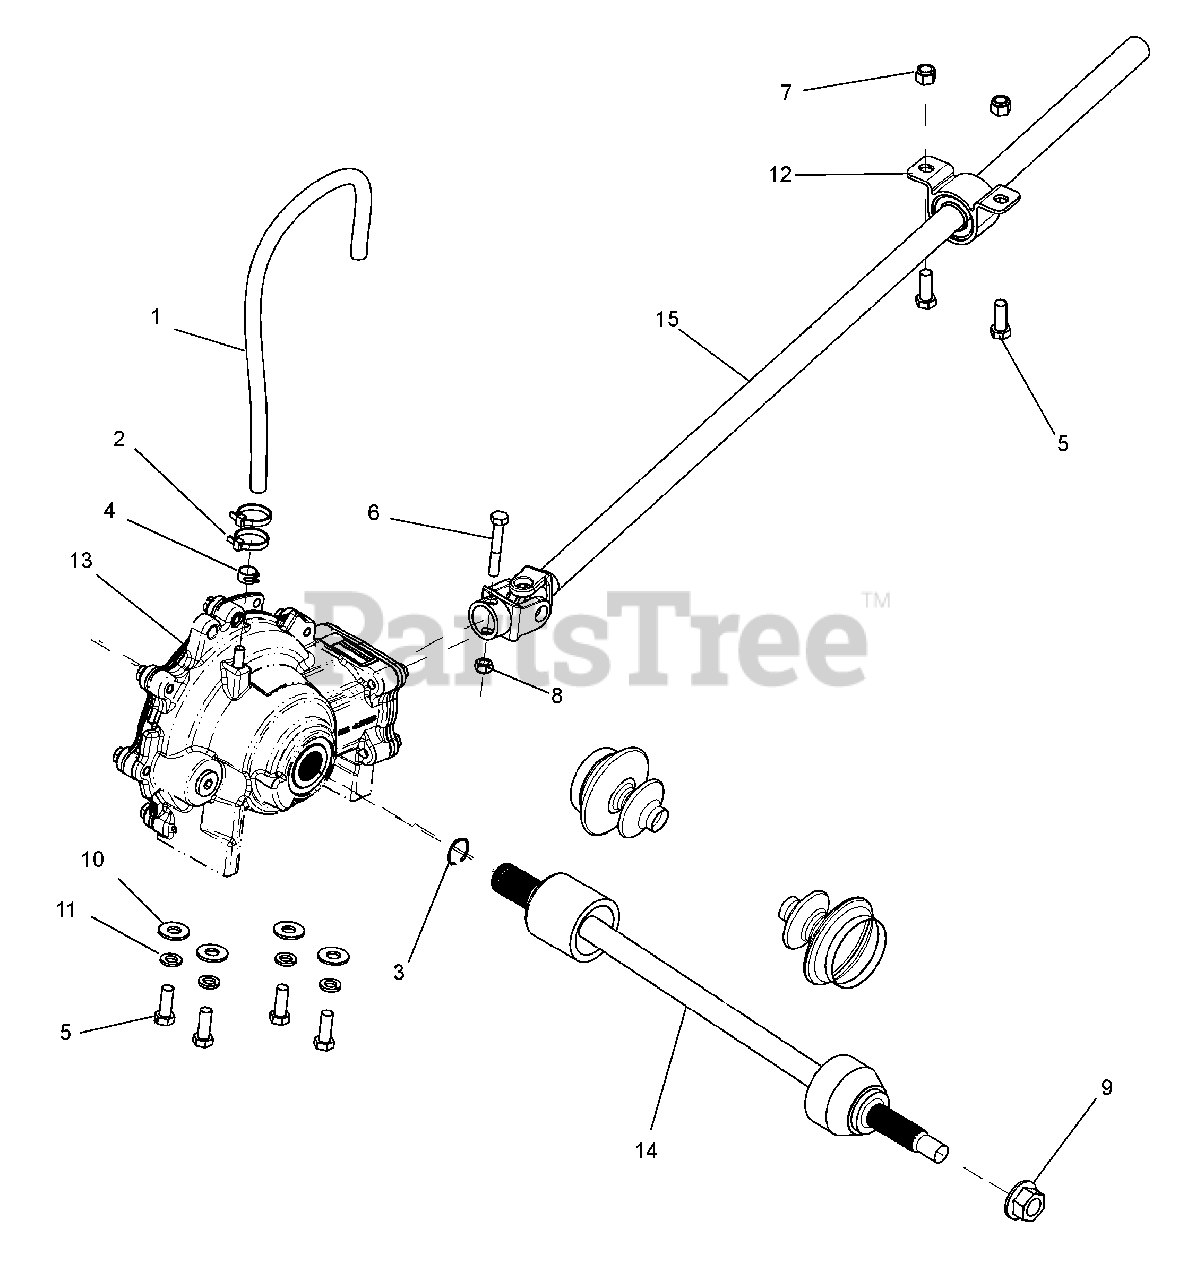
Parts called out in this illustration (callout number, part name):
1	VENT HOSE 17.5LG 4X4 GBOX
2	CABLE TIE 2 DIA MIN - BLK
3	SPRING CIR CLIP .95ODX.063WIRE
4	CLAMP, FUEL LINE
5	@BLT-HEX .38-16X1.00 GR5 YWZC
6	@BLT-HEX .31-18X2.00 GR5 YWZC
7	@NUT-LK-NYL .38-16 YWZC
8	@NUT-LK-NYL .312-18 YWZC
9	NUT HEX FLG T LCK M16X1.5 PLT
10	@WSHR-FL-STL.438X1.00X.083 YWZ
11	@WSHR-LK .38X.094 REG YWZC
12	BRG PB .75ID
13	FRONT DIFFERENTIAL W/ELE CLTCH
14	FRONT AXLE SHAFT STANDARD
15	FRONT HALF DRIVELINE 4X4 NT/ST
